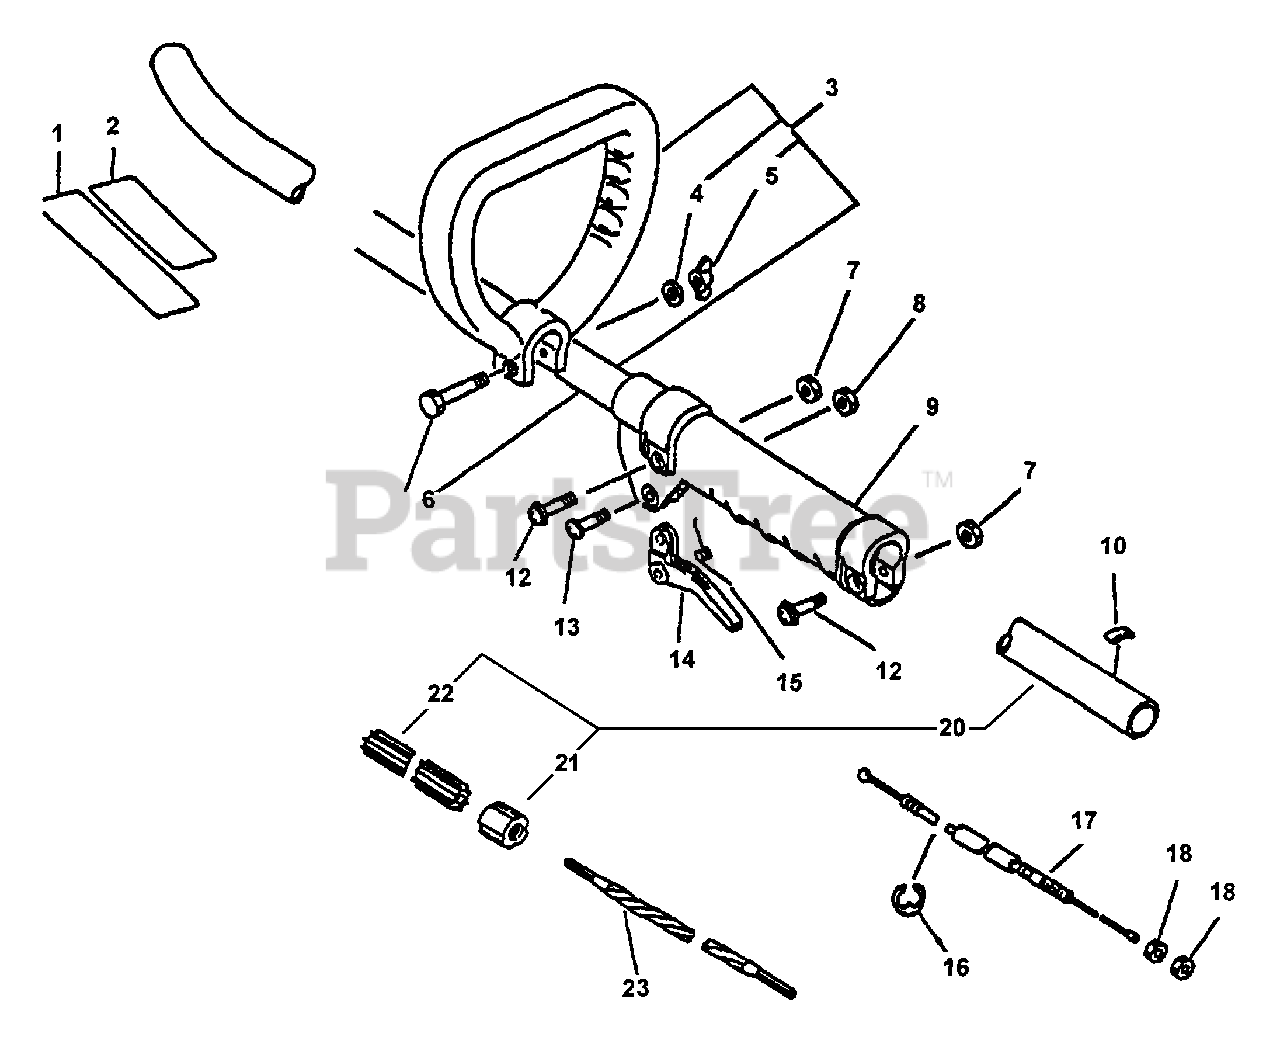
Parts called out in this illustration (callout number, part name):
1	LABEL - CAUTION
2	LABEL - CAUTION
3	HANDLE ASSY
4	WASHER - 1/4"
5	WINGNUT - 1/4-20
6	BOLT - 1/4-20 X 1-1/2"
8	LOCKNUT - 5
9	GRIP, HANDLE
10	LABEL - ALIGNMENT
12	SCREW - 5X25
13	SCREW - 5X30
14	TRIGGER, THROTTLE
15	SPRING, TRIGGER
16	RING, RETAINING - 5
17	CABLE, THROTTLE
20	MAIN PIPE ASSY
22	LINER - FLEXIBLE
23	DRIVESHAFT - FLEXIBLE
